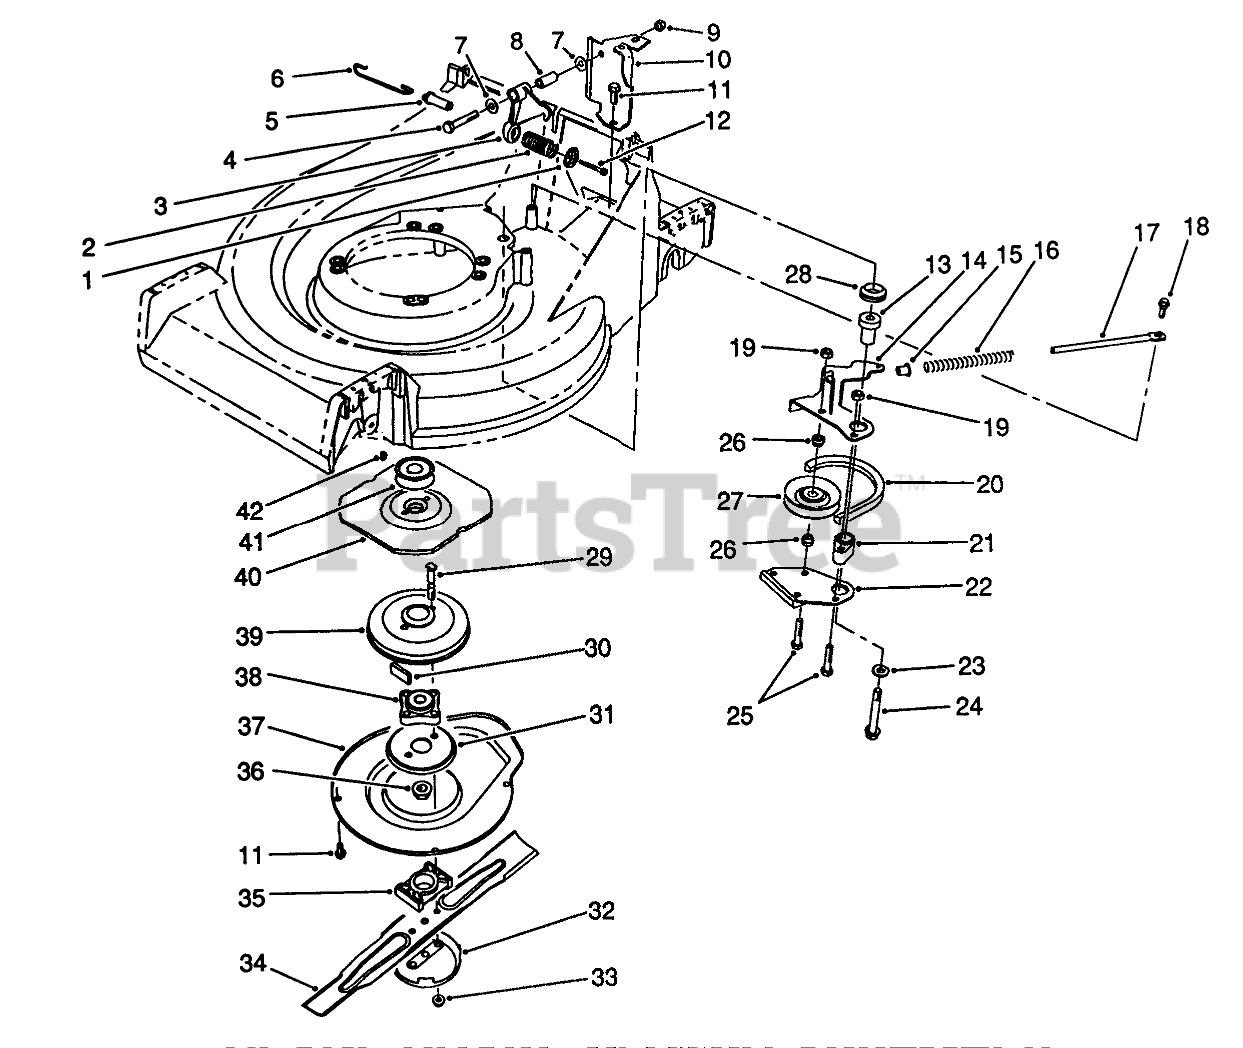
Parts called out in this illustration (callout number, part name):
1	RETAINER-SPRING
2	COMPRESSION SPRING
3	CRANK
4	SCREW-HH
5	SPRING PIN
6	CONTROL LINK
7	WASHER-PLAIN
8	STRAIGHT BUSHING
10	Bracket-Cable Support
11	SCREW-HWHTF
12	SCREW-HWHTF
13	BBC PM BUSHING
14	Lever
15	SPACER
16	COMPRESSION SPRING
17	SPRING ROD
18	SCREW-SHOULDER
19	NUT-LOCK, NI
20	V-BELT
21	BRAKE PLATE HUB
22	BRAKE SHOE
23	WASHER-PLAIN
24	3/8-16 X 2-3/4 CAPSCR
25	SCREW-HH
26	IDLER PULLEY HUB
27	PULLEY-IDLER
28	V-RING SEAL
29	BOLT-BLADE
30	DAMPENER-VIBRATION
31	Screen-BBC
32	Anti Scalp Cup
33	NUT-LOCK
34	Key
35	SPACER-BLADE
36	NUT-LOCK, NI
37	Cover
38	HUB ASM
39	BRAKE DRUM
40	FLYWHEEL - BBC
41	PULLEY
42	KEY-WOODRUFF
